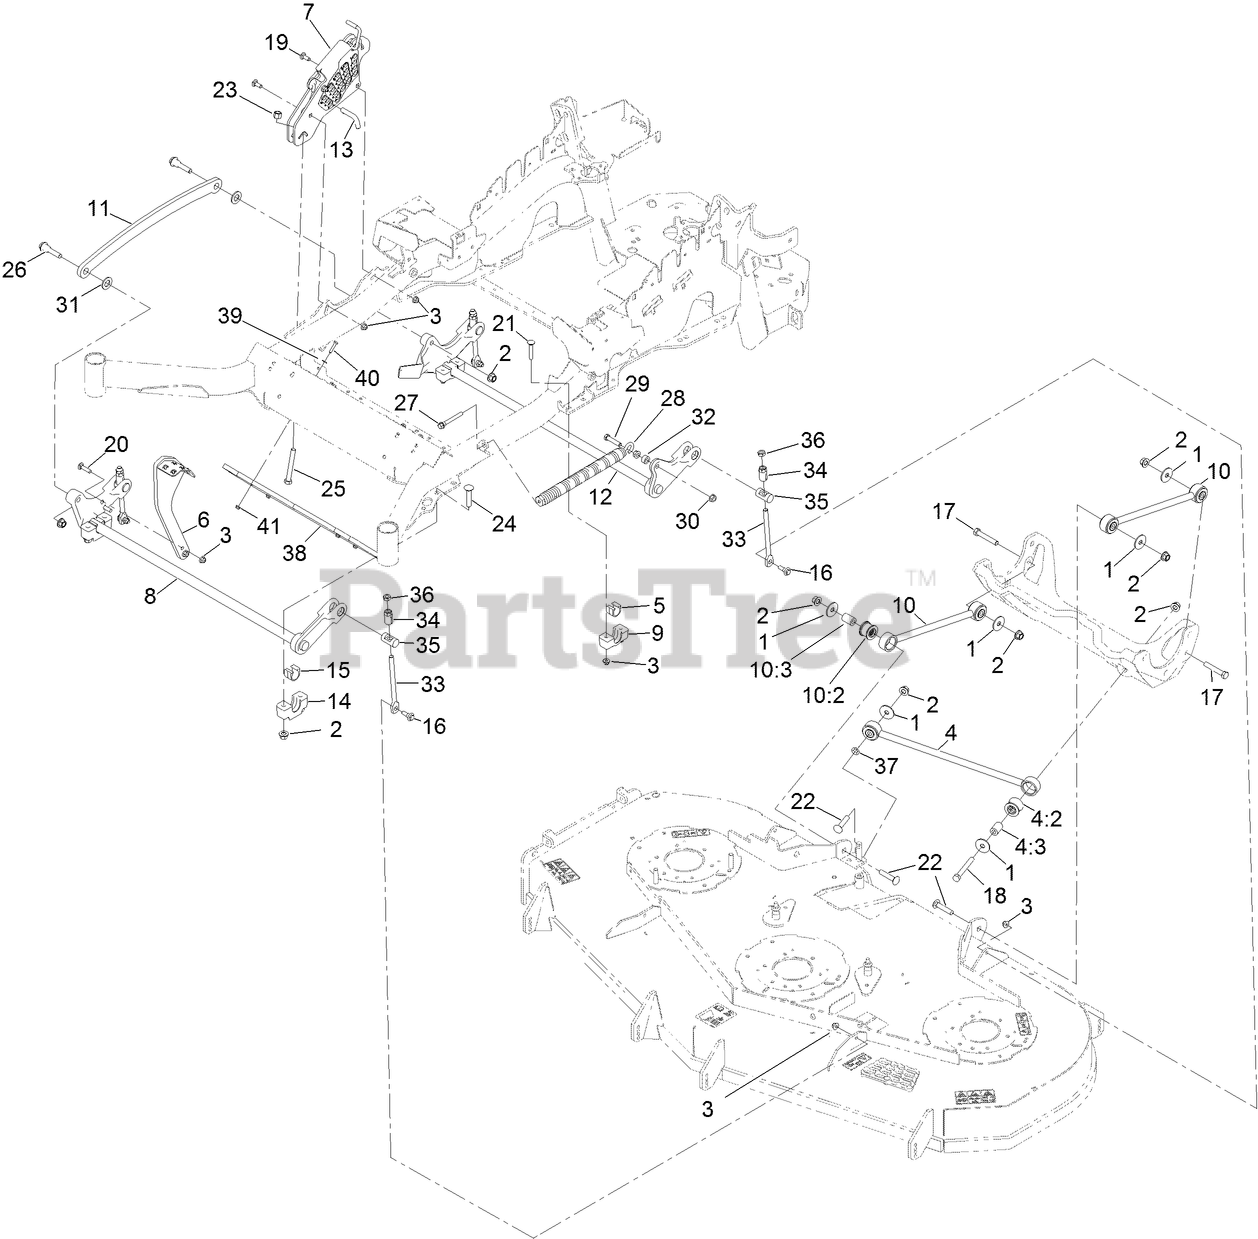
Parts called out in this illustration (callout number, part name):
1	WASHER-THRUST
2	NUT-LOCK
3	NUT-HF, NI
4	PANHARD ROD ASM
4:2	BUSHING-SUSPENSION, RUBBER
4:3	SPACER
5	BEARING-CROSS SHAFT, REAR
6	LEVER-FOOT
7	HOC ASM
8	DECKLIFT-FRONT
9	SUPPORT-CROSS SHAFT, BEARING REAR
10	DECK STRUT ASM
10:2	BUSHING-SUSPENSION, RUBBER
10:3	SPACER
11	LINK-LIFT, DECK
12	LIFT-DECK, REAR
13	PIN-HOC
14	SUPPORT-CROSS SHAFT, BEARING
15	BEARING-CROSS SHAFT, FRONT
16	SCREW-SHOULDER, HHF
17	SCREW-HH
18	SCREW-HH
19	BOLT-CARR
20	SCREW-CARR
21	SCREW-CARR
22	SCREW-CARR
23	NUT-LOCK, NI
24	BOLT-CARR
25	BOLT-TAP
26	SCREW-HHF, SHOULDER
27	BOLT-SHOULDER
28	SPRING-EXTENSION
29	SCREW-HH
30	NUT-HF
31	WASHER-FLAT
32	SPACER
33	LINK-ADJUSTER, DECK LIFT
34	ADJUSTER-LIFT, DECK
35	TRUNNION
36	NUT-JAM
37	NUT-PUSH
38	WEIGHT-TOE BOARD
39	WASHER-FLAT
40	SCREW-HH
41	NUT-HF
